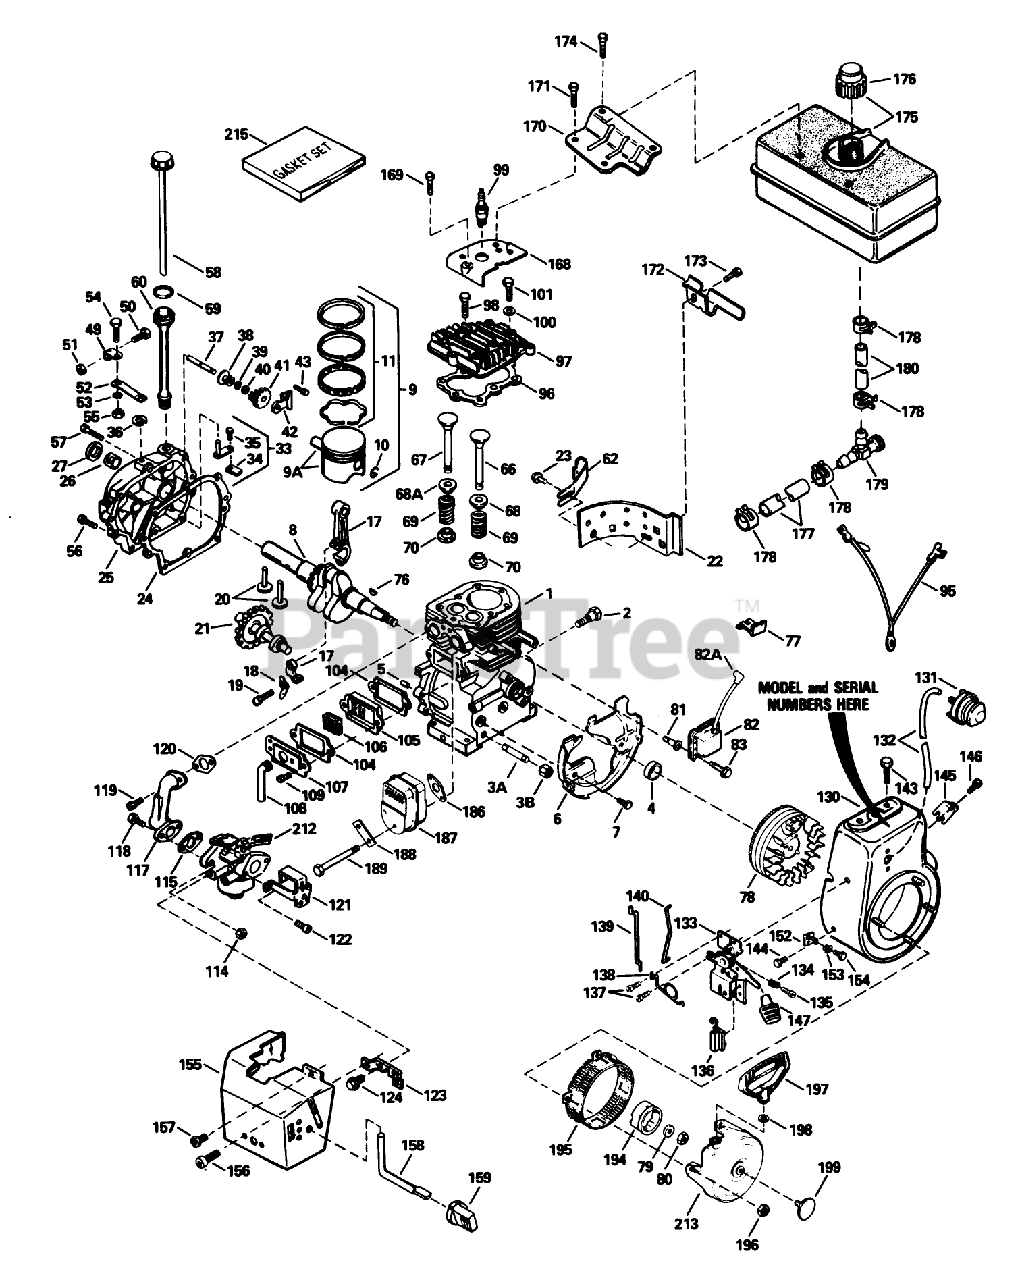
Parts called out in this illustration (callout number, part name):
1	Cylinder Asm (Includes 2, 20, 72)
2	Screw (1/4-20x1/2)
3A	Nipple-Pipe
3B	Cap-Pipe
4	Seal-Oil
5	Pin-Dowel
6	Baffle-Blower Housing
7	Screw (1/4-20x19/32)
8	Crankshaft
9	Piston, Pin Ring Assy.(Std.) (Incl. Ref. #24A, 25 26)
9A	Piston Pin Assy. (Std.) (Incl. Ref. #26)
11	Ring Set (Std.)
17	Rod Assy., Connecting (Incl. Ref. #26 27)
18	Dipper-Oil
19	Bolt-Rod
20	Lifter-Valve
21	Camshaft (MCR)
22	Extension-Housing, Blower
23	Screw
24	Cylinder Cover Gasket
25	Cover-Cylinder (Includes 71, 75, 80)
26	2025A77 WIZARD ROTA
27	Seal-Oil
33	Rod, Governor (Incl. Nos.62 63)
34	Yoke-Governor
35	Screw (6-40x5/16)
36	Ring-Retaining
37	Shaft-Governor
38	Spool-Governor
39	Washer-Flat
40	Ring-Retaining
41	Gear Assy., Governor (Incl. Ref. #45)
42	Bracket-Gear, Governor
43	Screw (10-24x1/2)
49	Clamp-Lever, Governor
50	Screw
51	Nut-Lock
52	Lever-Governor
53	Washer-Lock
54	Screw
55	Nut-Lock
56	Screw (1/4-20x1-11/16)
57	Screw (1/4-20x1-3/16)
58	Dipstick
59	O-Ring
60	Tube-Fill, Oil
62	Clip-Tube, Fill
66	Valve, Exhaust (Standard)(Incl. No. 9)
67	Valve, Intake (Std.) (Incl. Ref. #58)
68	Cap-Spring, Valve
68A	Seal-Intake Valve
69	Spring-Valve
70	Keeper-Spring, Valve
76	Key-Flywheel
77	Clip-Wire
78	Flywheel (W/Ring Gear)
79	Washer-Belleville
80	Nut-Flywheel
82	Solid State ASM
82A	Cover-Spark Plug
83	Screw
95	Ground Wire
96	Gasket-Cylinder Head
97	Head Cylinder
98	Screw (5/16-18x1-1/2)
99	Spark Plug-Resistor (R J19 L M)
100	Washer-Flat
101	Screw (5/16-18x1-25/32)
104	Gasket-Breather
105	Body-Breather
106	Element-Breather
107	Cover-Valve
108	Tube-Breather
109	Screw
114	Nut and Lock Washer (1/4-28)
115	Gasket-Carburetor To Intake Pipe
117	Pipe-Intake
118	Screw (1/4-28x1)
119	Screw (T-30, 5/16-18x1-3/32)
120	Gasket-Intake
121	Bracket-Choke
122	Screw (10-32 x 1/2)
123	Bracket-Carburetor
124	Screw (8-32x27/64)
130	Housing-Blower
131	Primer-Asm
132	Line-Primer
133	Control Bracket Assembly (Incl. Ref. #134-136 138)
134	Spring-Compression
135	Screw
136	Terminal
137	Screw (10-32 x 1/2)
138	Spring-Throttle
139	Link-Governor
140	Link-Throttle
143	Screw (5/16-18x3/4)
144	Screw
145	Screw
146	Screw (8-32 x 3/8)
147	Knob-Control
152	Bracket
153	Grommet
154	Screw (8-32 x 3/8)
155	Cover-Carburetor
156	Screw (10-32 x 3/8)
157	Screw (10-32x1/2)
158	Rod-Choke
159	Knob-Control
168	Cover-Cylinder Head
169	Screw (1/2-20x5/8)
170	Bracket-Tank, Fuel (Black)
171	Screw
172	Bracket-Tank, Fuel
173	Screw (1/4-20x19/32)
174	Screw (1/4-15x7/8)
175	Tank Assy., Fuel (Incl. No. 115)
176	Cap, Fuel
177	Line-Fuel
178	Clamp-Line, Fuel
179	Valve-Shut Off
180	Line-Fuel (8.62)
186	Gasket Exhaust
187	Muffler
188	62513 SNWTHWR W/284
189	Screw
194	Cup-Starter
195	Screen-Starter
196	Nut and Lock Washer (1/4-28)
197	Handle-Starter, Mitten Grip
198	Washer
199	Plug Starter
212	Carburetor (Incl. Ref. #75)
213	Starter-Rewind
215	Gasket Set (Incl. items marked *) Order As Accessory.
